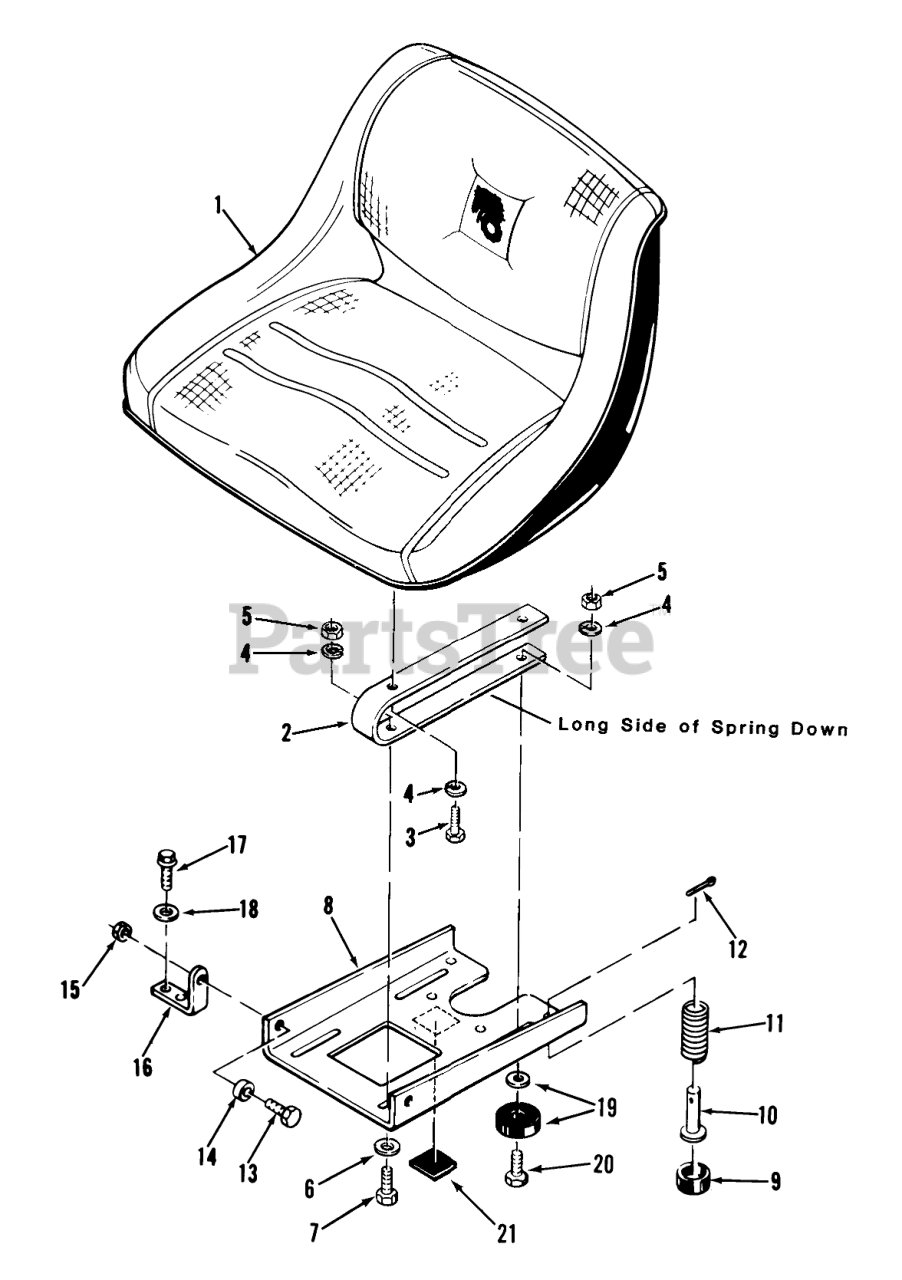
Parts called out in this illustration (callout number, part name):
1	Seat 312, 414
1	Seat
2	Spring
3	Bolt
4	Lockwasher
5	Nut
6	WASHER 5/16 SAE
7	HHCS
8	Pivot Plate
11	SPRING
12	Cotter Pin
13	HHCS
14	BUSHING
15	Nut
16	BRACKET-PIVOT
17	SEAT BOLT FOR C195
17	Bolt
18	WASHER 5/16 SAE
19	BUMPER
19	WASHER 5/16 SAE
20	Bolt
20	HHCS
21	BUMPER
